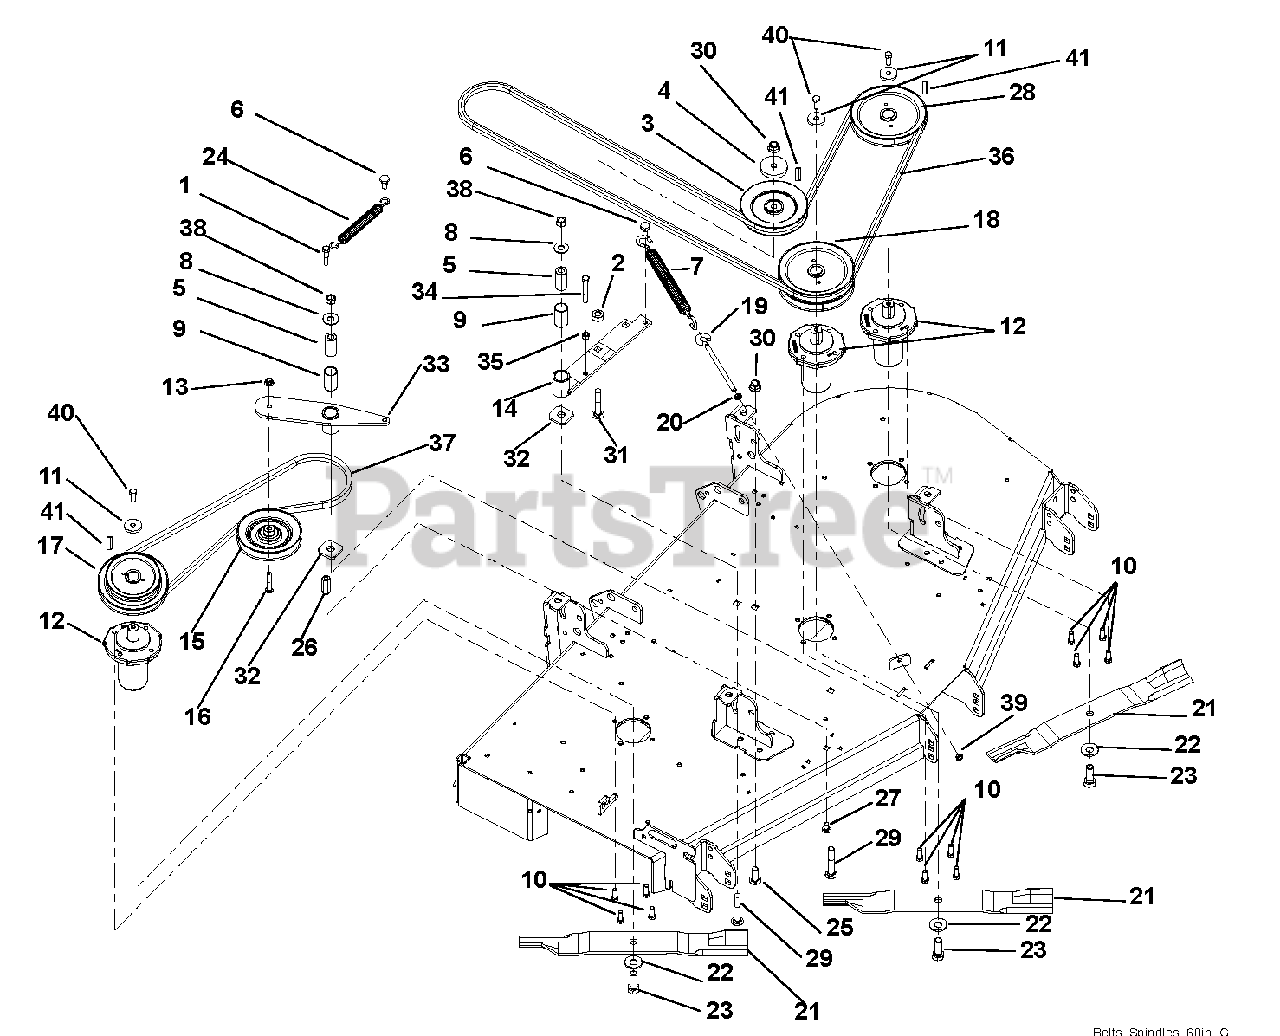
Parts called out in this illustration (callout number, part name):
1	Bolt, Hex .38-16 x 1.50
2	Bushing, Spacer .502 x .997 x .50
3	Sheave, .50" ID x 6.00" OD V-Idler
4	Cap, Idler Bearing Sealing
5	Bushing, Spacer .505/.500 x .999/.996 x 2.05/2.03
6	Bolt, Shoulder EP .38-16 x .30 Hex
7	Spring, Extension (Deck Idler)
8	Washer, Flat Steel .563 x 1.38 x .109
9	Bushing, 1.00 x 1.125 x 1.936
10	Bolt, Hex .38-16 x 1.00
11	Retainer, Sheave
12	Spindle Assembly
13	Nut, Locking Nylon Flange .38-16
14	Weldment, Idler Arm
15	Pulley, Flat Idler Engine to Deck
16	Bolt, Hex .38-16 x 2.00
17	Pulley, Double 1" ID x 6.75" & 5.25" OD
18	Pulley, Double 1" ID x 6.75" OD
19	Bolt, .38-16 x 5.50 .62 Diameter Eye
20	Nut, Hex Jam .375-16
21	Blade, 20.50" Mower
22	Washer, Bellville .63 x 1.625 x.14
23	Bolt, Hex .62-18 x 1.75 Grade 8 (Torque to 115-125 ft. lbs., 155 – 169 N-m)
24	Spring, Extension
25	Bolt, Round Head Square Neck .50-13 x 1.5, Full Thread
26	Nut, Coupling .375-16 x 1.75
27	Bolt, Round Head Square Neck .38-16 x 1.00
28	Pulley, V, 1" ID x 6.75" OD
29	Bolt, Round Head Square Neck .50-13 x 3.25
30	Nut, .50-13 Nyloc Flange
31	Bolt, Round Head Square Neck .50-13 x 3.00
32	Washer, Flat .640 x 1.75 x .250
33	PT160 Deck Idler Arm Weldment, Black
34	Bolt, Hex .38-16 x 2.75
35	Nut, Hex .38-16
36	Belt, 133.00 Wrapped Hex
37	Belt, B 63.00 Raw Cogged
38	Nut, Locking Center .50-13
39	Nut, Lock Center Jam .375-16
40	Bolt, Hex .38-16 x 2.75 Grade 8
41	Key, Square .25 x .25 x 1.00
